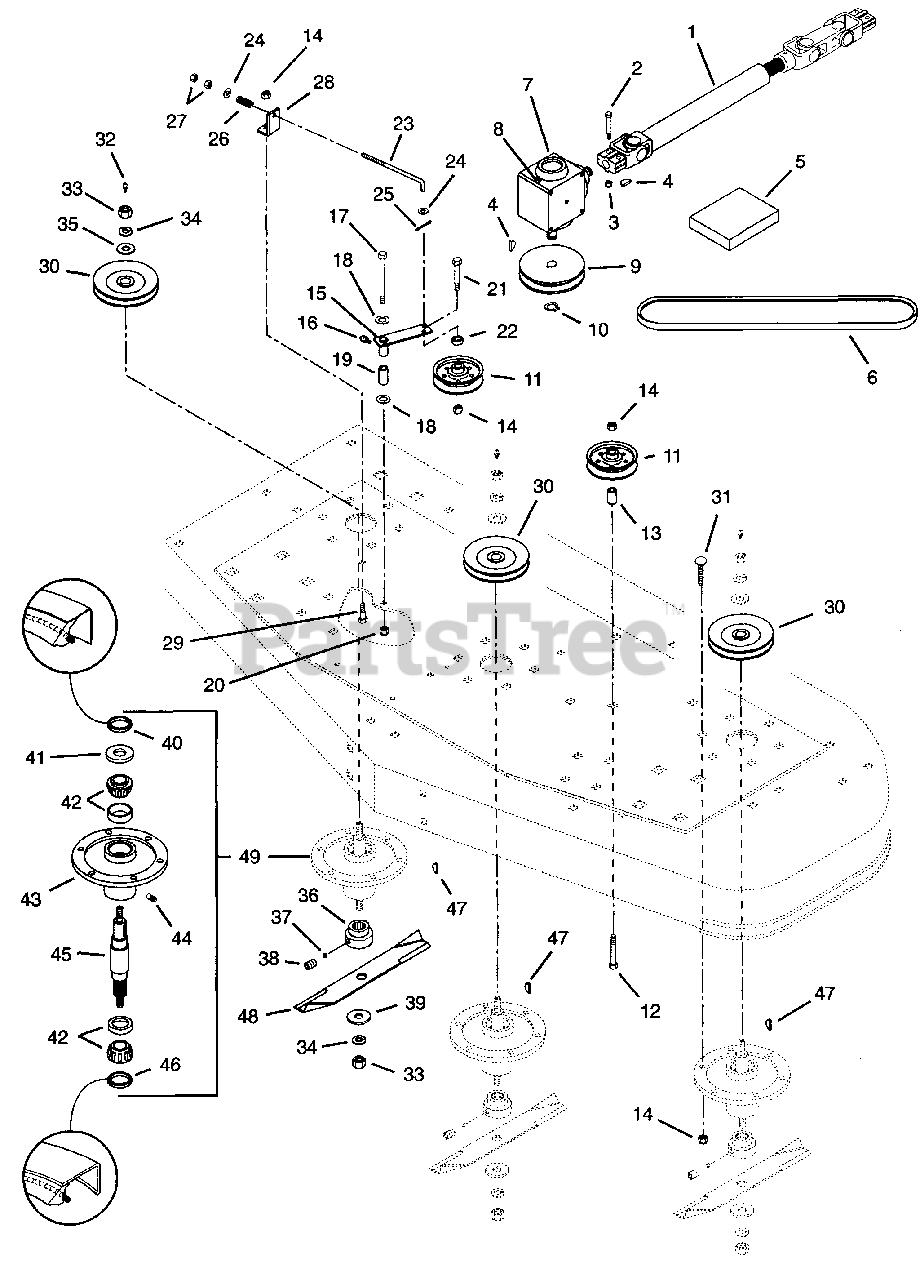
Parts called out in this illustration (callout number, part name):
1	C.V. Universal Joint - 60" Deck
1	C.V. Universal Joint - 72" Deck
2	Bolt-Hex .31-18 x 1.75 Grade 5
3	Nut-Locking-Nylon .312-18 Grade 2
4	Key, Woodruff .25 x .875
5	Kit, Repair, U-Joint
6	V-Belt B-Section 82.375 x .672
6	V-Belt A-Section 94.8 x .656
7	Gearbox, Right Angle 1:1
8	Plug, 1/8 Vent
9	Sheave, Gear Box
10	Ring-Retaining-External .821 x .078
11	Idler-Flat-Pulley 6.75 x .510
12	Bolt-Hex .50-13 x 2.75 Grade 5
12	Bolt-Hex .50-13 x 2.00 Grade 5
13	Spacer .562 x .975 x 1.00
13	Spacer .516 x .875 x .300
14	Nut-Locking-Nylon .375-16 Grade 2
15	Weldment, Idler Pivot
16	Fitting-Lube .25-28 x .256
17	Bolt-Hex .50-13 x 3.375
18	Washer-Flat-Steel .500 x 1.250 x .083
19	Spacer .505 x .855 x 2.50
20	Nut-Locking .50-13 Grade 5
21	Bolt-Hex .38 x 1.75 Grade 5
22	Spacer .516 x .875 x .300
23	Rod, Idler
24	Washer-Flat-Steel .406 x .812 x .062
25	Pin-Cotter .09 x .75
26	Spring-Compression .125 x .78 x 1.00
27	Nut-Hex .375-24 Grade 2
28	Support, Spring
29	Bolt-Hex .38-16 x 1.00 Grade 5
30	Weldment, Sheave
31	Bolt-Round Head Square Neck .38-16 x 1.50
32	Fitting-Lube 1/8
33	Nut-Hex .625-11 Grade 2
34	Washer - Lock .625 x .156
35	Washer-Flat-Steel .687 x 1.312 x 1.50
36	Hub
36	Weldment, Blade Cradle
37	Plug
38	Screw-Set .25-20 x .25
39	Washer
39	Washer-Flat-Steel .687 x 1.312 x 1.50
40	Seal 1.987 x 1.500 x .313
41	Washer-Flat-Steel 1.007 x 1.542 x .062
42	Assembly, Bearing Cup and Cone
43	Bearing, Housing
44	Relief Fitting
45	Shaft, Spindle
46	Seal 1.987 x 1.375 x .313
47	Key-Woodruff .25 x 1
48	Blade
48	Blade, 72" Mower
49	Service Kit
